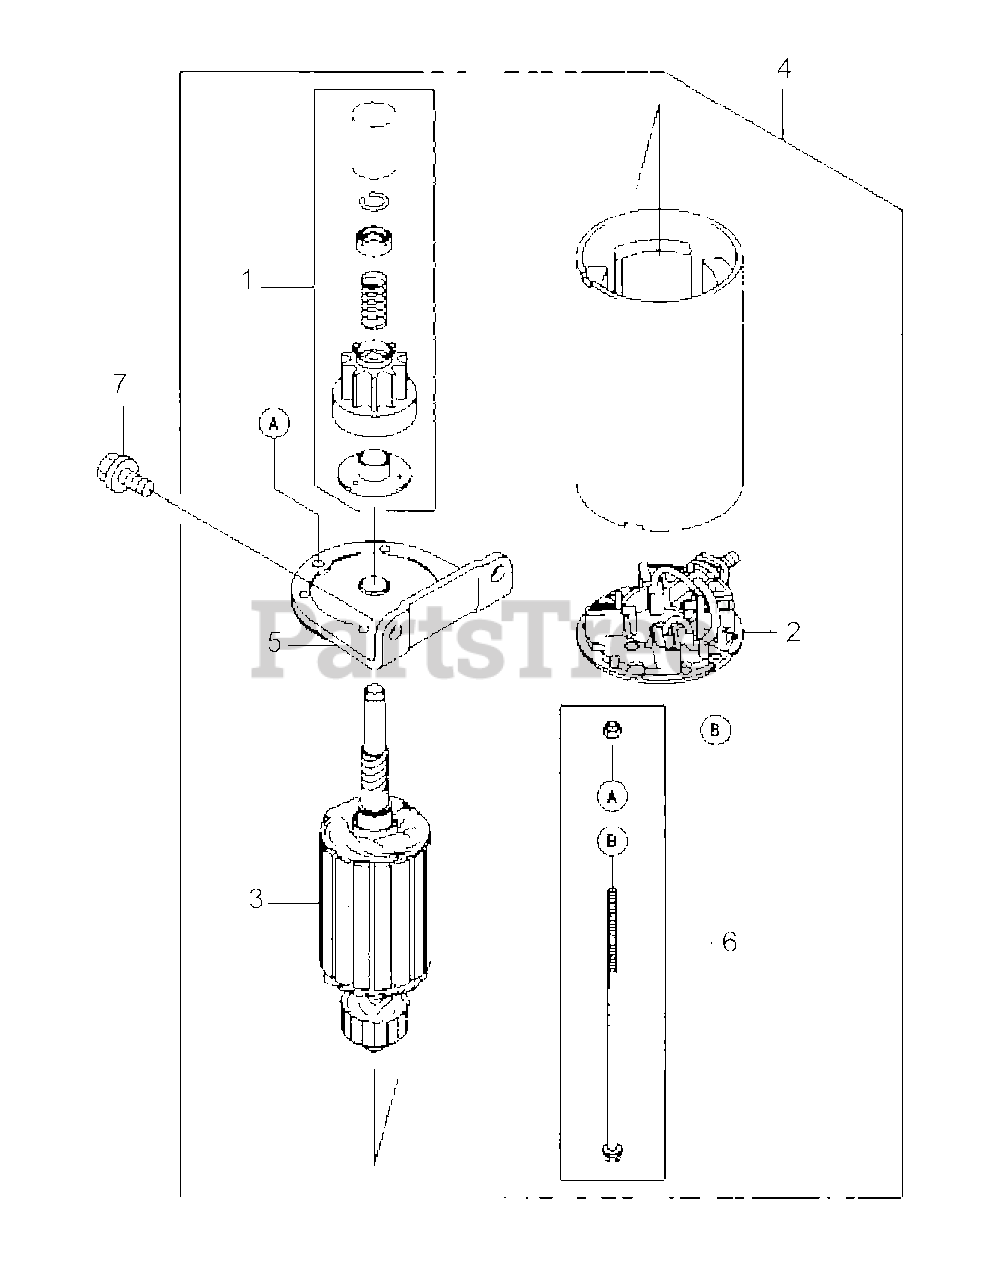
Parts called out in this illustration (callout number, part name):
1	GEAR ASSY.
4	ELECTRIC STARTER
5	BRACKET ASSY
7	FLANGED BOLT
